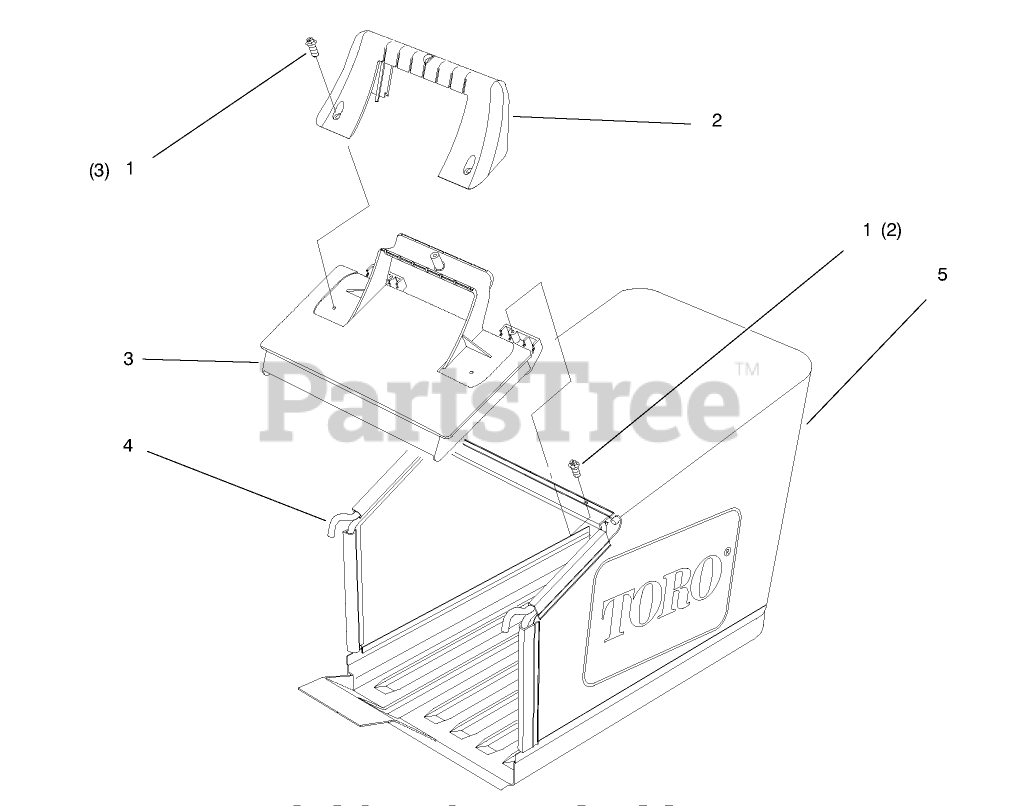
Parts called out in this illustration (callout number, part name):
1	SCREW-PPH
2	HANDLE-DOOR
3	DOOR-BAG
4	Frame
5	BAG-GRASS
